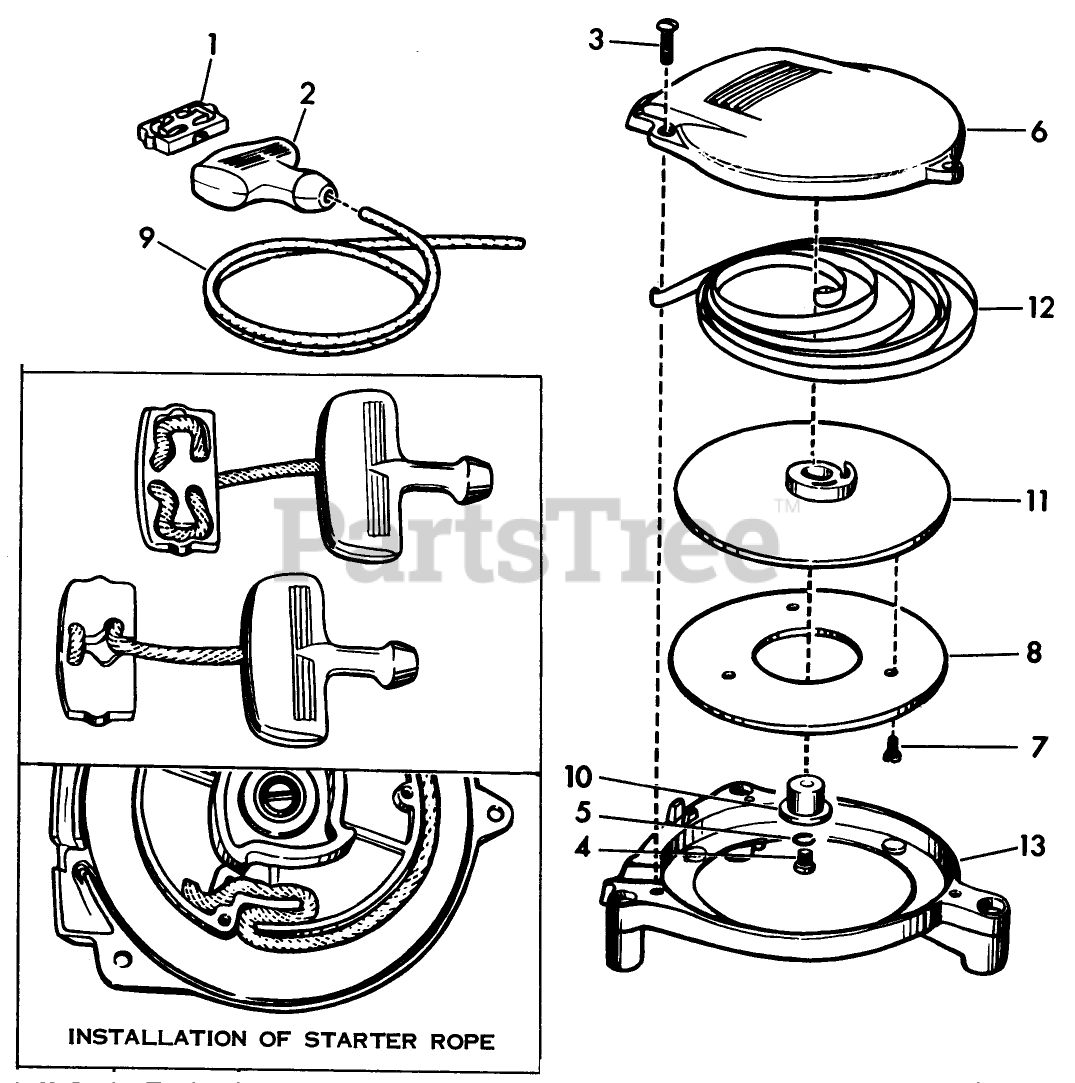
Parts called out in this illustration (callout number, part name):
4	Screw-Pulley to Cap
5	Washer-Lock, Pulley
12	RECOIL SPRING
13	Base-Starter
